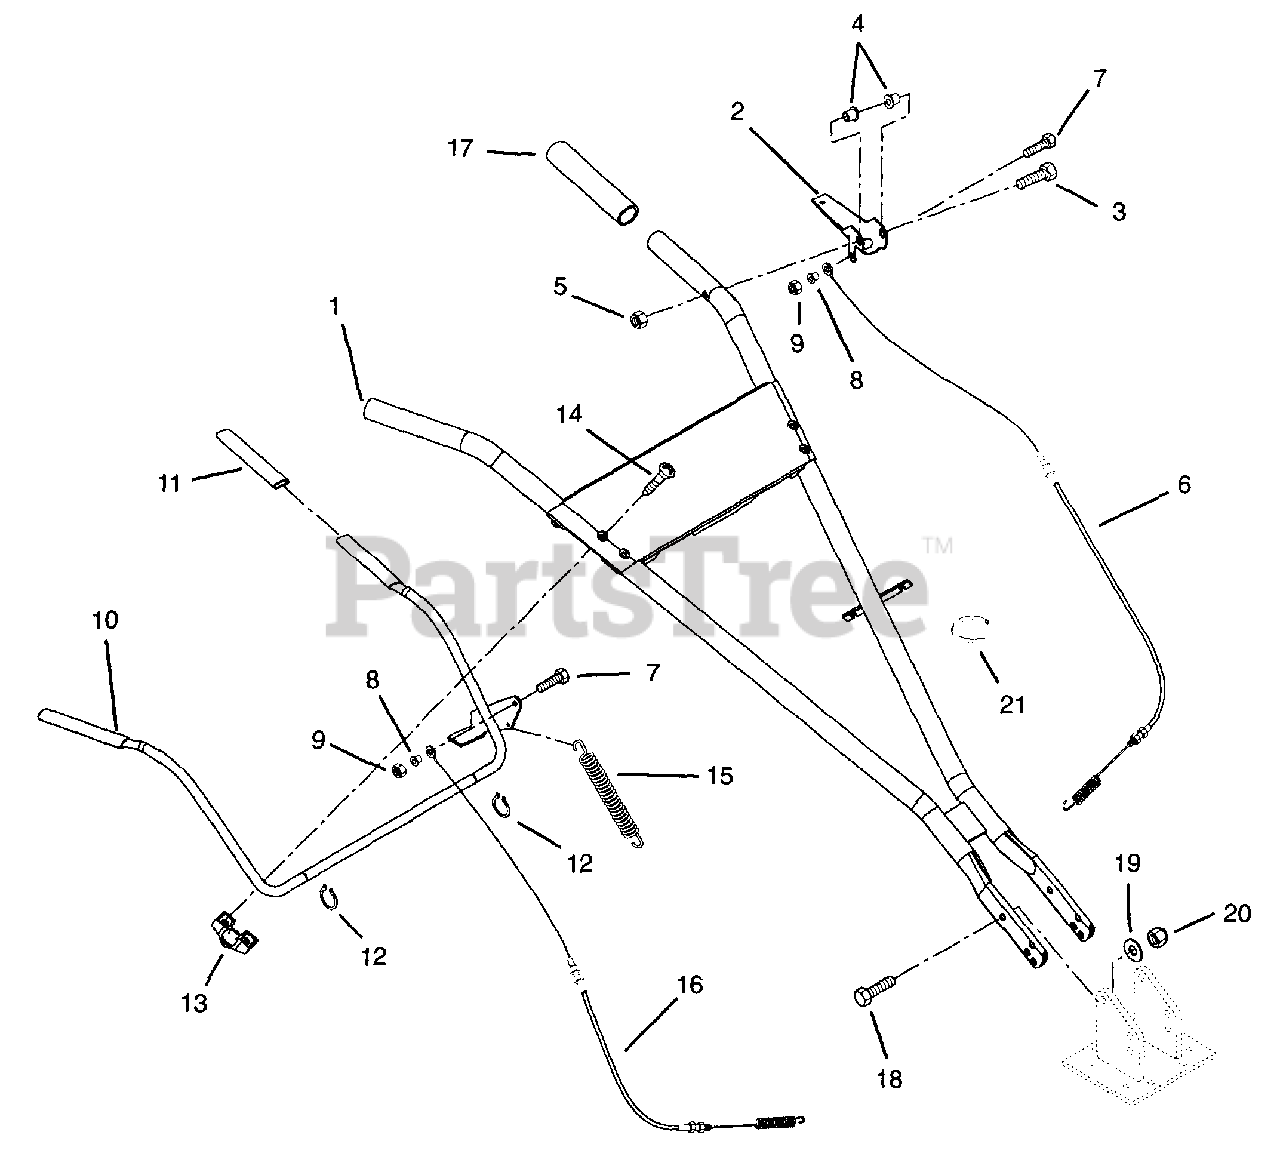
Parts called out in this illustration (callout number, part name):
1	HANDLEBAR
2	HANDLE, REVERSE
3	@BLT-HEX .31-18X2.25 GR5 YWZC
4	BSHG-FLG .325X.465X.333X.685
5	@NUT-LK-CTR .31-18 YWZC
6	CABLE, REV. SER 18"
7	@BLT-HEX .25-20X1.00 GR5 YWZC
8	BSHG-FLG .253X.373X.385X.500
9	@NUT-LK-CTR .25-20 YWZC
10	BAIL, FWD
11	GRIP, TILLER - OPC
12	RG-RTNG-EXT .500X.042 (E)
13	PIVOT, BAIL
14	SCR-TAP 12-24X1.50 CROVH YZ BT
15	SG-TENS .051X.50X5.12 WLD 10.4
16	CABLE, FWD. SER. 18"
17	HANDLEGRIP
18	@BLT-HEX .38-16X1.00 GR5 YWZC
19	@WSHR-FL-STL.438X1.00X.083 YWZ
20	@NUT-LK-CTR .38-16 YWZC
21	TIE WRAP, BLACK LG 7.31
